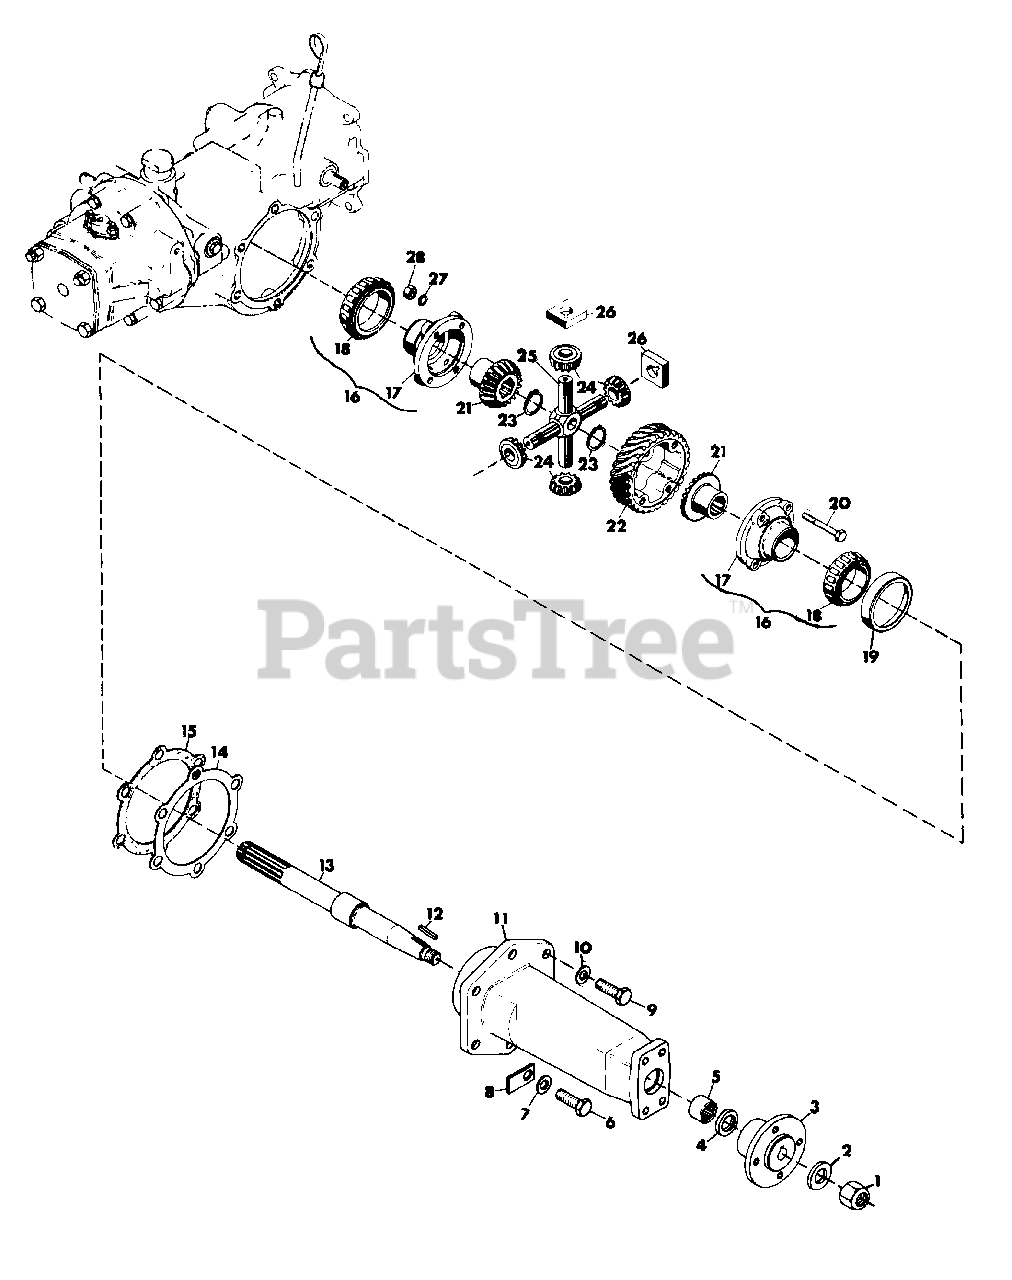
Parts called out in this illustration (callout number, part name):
1	NUT, LOCK 5/8-11
2	WASHER, FLAT .656X1.312X.095
3	HUB
4	SEAL, OIL 1X1.437X.312
5	BEARING, NEEDLE 1X1.25X.75
6	BOLT, 1/2-13X1 NYLON INSERT
7	WASHER, FLAT .531.X1.062X.095
8	WASHER, OIL DRAIN
9	BOLT, HEX 1/2-13X1
10	WASHER, LOCK 1/2
11	HOUSING, AXLE
12	KEY, HUB .187X1.500
13	AXLE
14	SHIM, AXLE HOUSING .005
15	GASKET, AXLE HOUSING
16	ASSEMBLY, DIFFERENTIAL HOUSING
17	HOUSING, DIFFERENTIAL
18	CONE, ROLLER BEARING
19	CUP, ROLLER BEARING
20	BOLT, HEX 5/16-24X2.75
21	GEAR, DIFFERENTIAL BEVEL
22	GEAR, WORM 8 START
23	RING, RETAINING 1.000 SHAFT
24	GEAR, SPIDER BEVEL
25	PIN, SPIDER
26	BLOCK, DRIVE
27	WASHER, LOCK 5/16
28	NUT, HEX 5/16-24
